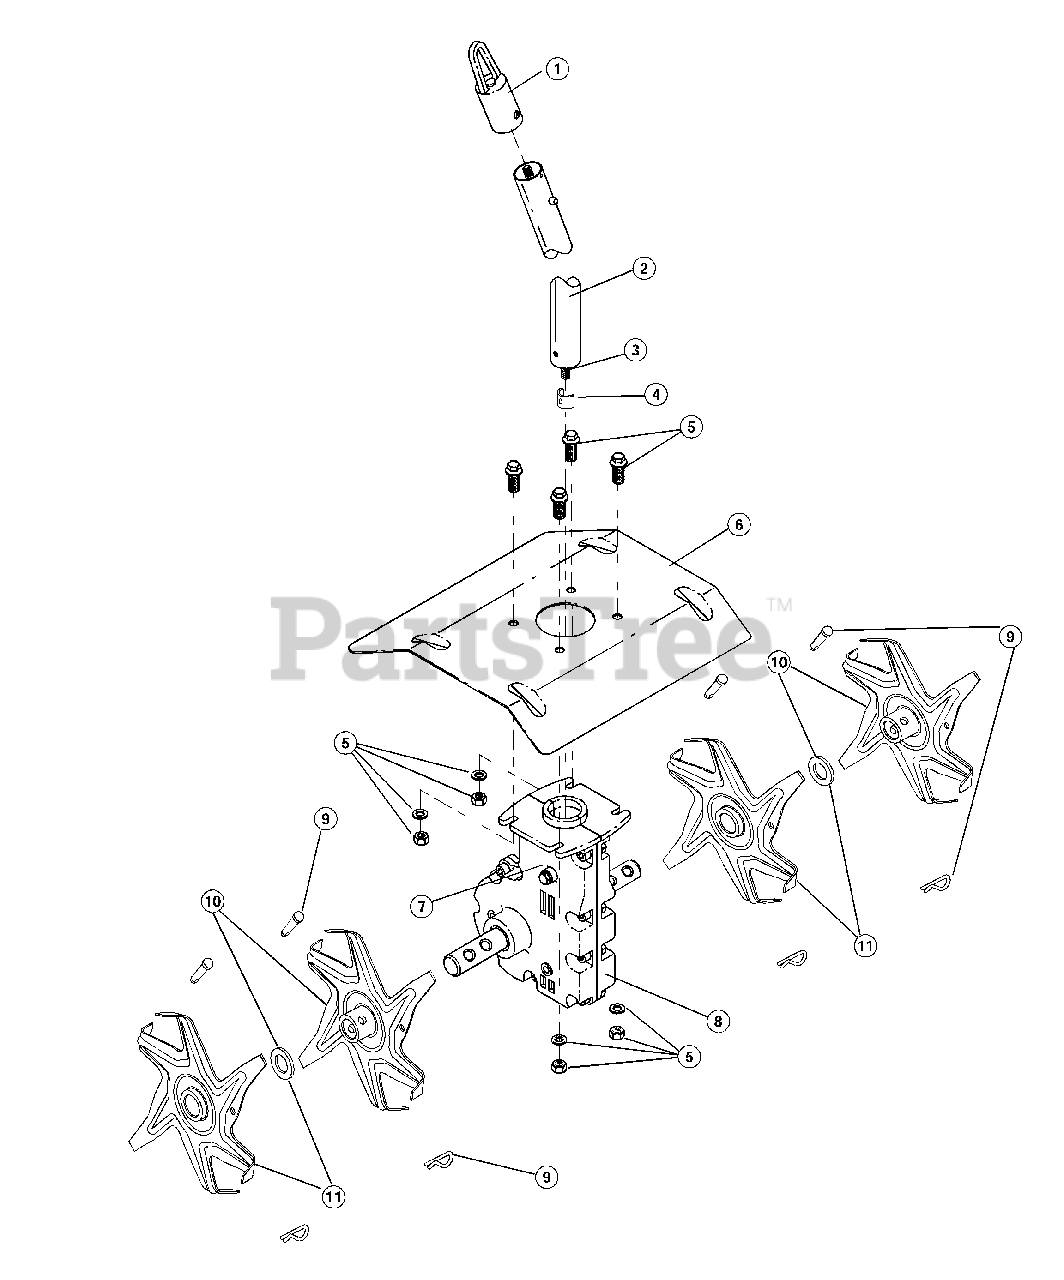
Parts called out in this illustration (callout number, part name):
1	Accessory Hanger
2	Drive Shaft Housing Assembly
3	Flexible Drive Shaft
4	Retainer Sleeve
5	Guard Mounting Hardware Set
7	Bolt
8	Gear Box Assembly
9	Tine Fastener Assembly
10	Tine Assembly (Left Outer or Right Inner)
11	Tine Assembly (Left Inner or Right Outer)
